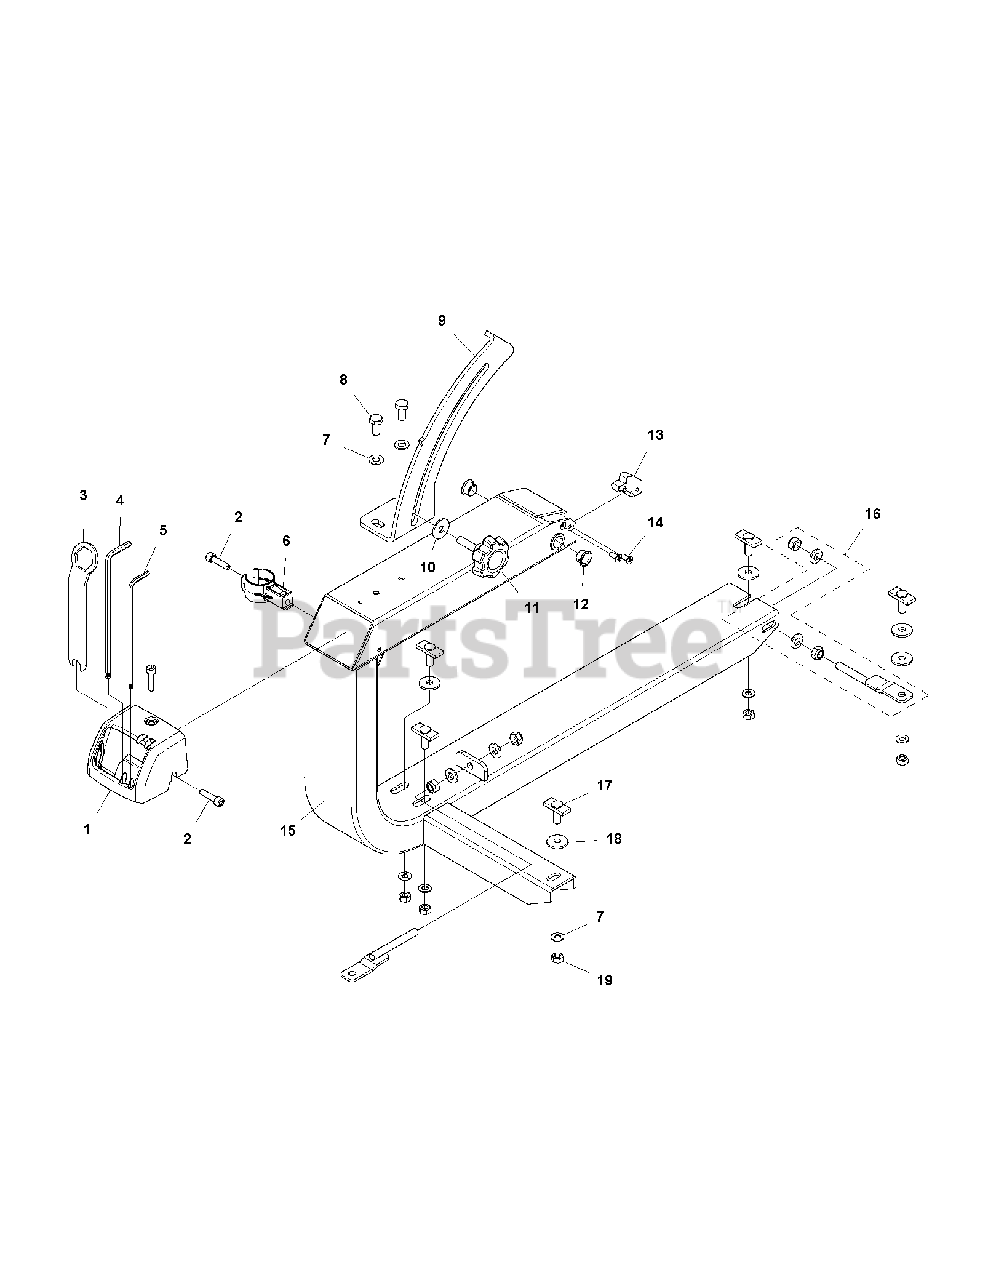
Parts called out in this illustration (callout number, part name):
2	SCREW IHSCM
7	WASHER
8	SCREW EHHM
19	HEXAGON LOCKING NUT
